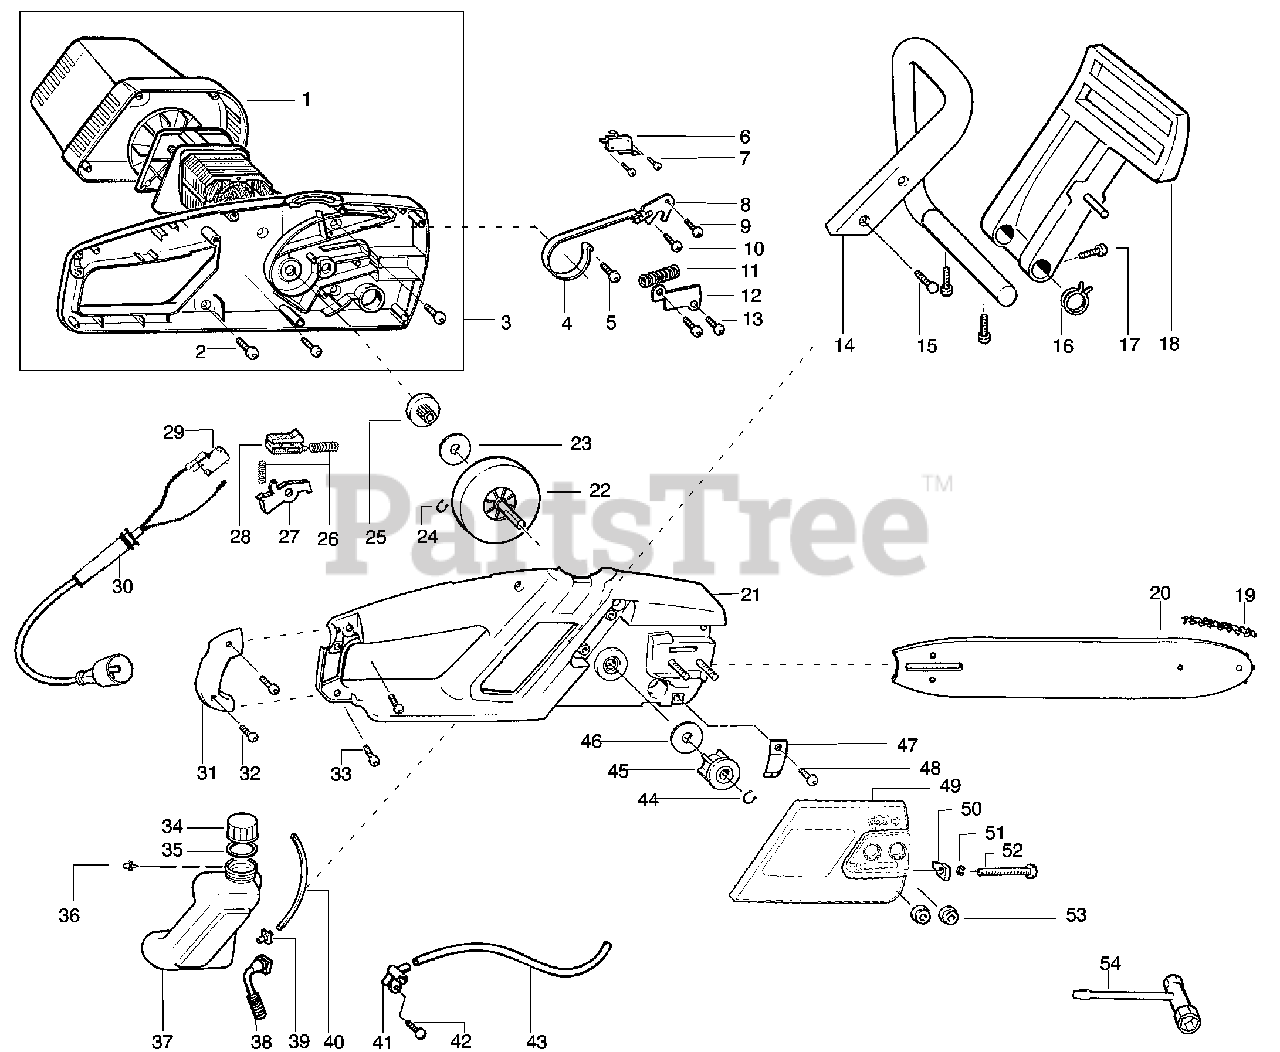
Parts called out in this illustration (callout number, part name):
1	Motor Cover
3	Housing/Motor Ass'y.
4	Brake Band
6	Switch-Chain Brake
7	Screw
8	Front/Rear Link Ass'y.
9	Screw-Brake Pivot
10	Screw
11	Spring-Brake
12	Cover Spring
14	Front Handle
16	Spring-Handguard
18	Handguard
19	Chain 18"
21	Housing Cover
22	Gear Drive
23	Washer-Thrust
24	Ring-Retainer
26	Spring-Trigger
28	Lockout Button
29	Switch-Momentary
30	Cord Set
31	Cover-Access
34	Oil Cap
35	O-Ring
36	Check Valve
37	Oil Tank Ass'y.
38	Oil Pickup Ass'y.
39	Oil Pickup Fitting
40	Inlet Line
41	Oil Pump Ass'y.
43	Outlet Line
44	Ring-Retainer
45	Sprocket
46	Washer-Sprocket
47	Chain Catcher
49	Bar Clamp
50	Pin-Bar Adjust
51	Retainer-Bar Adjust
52	Screw-Bar Adjust
53	Nut-Bar Mounting
54	Bar Wrench
